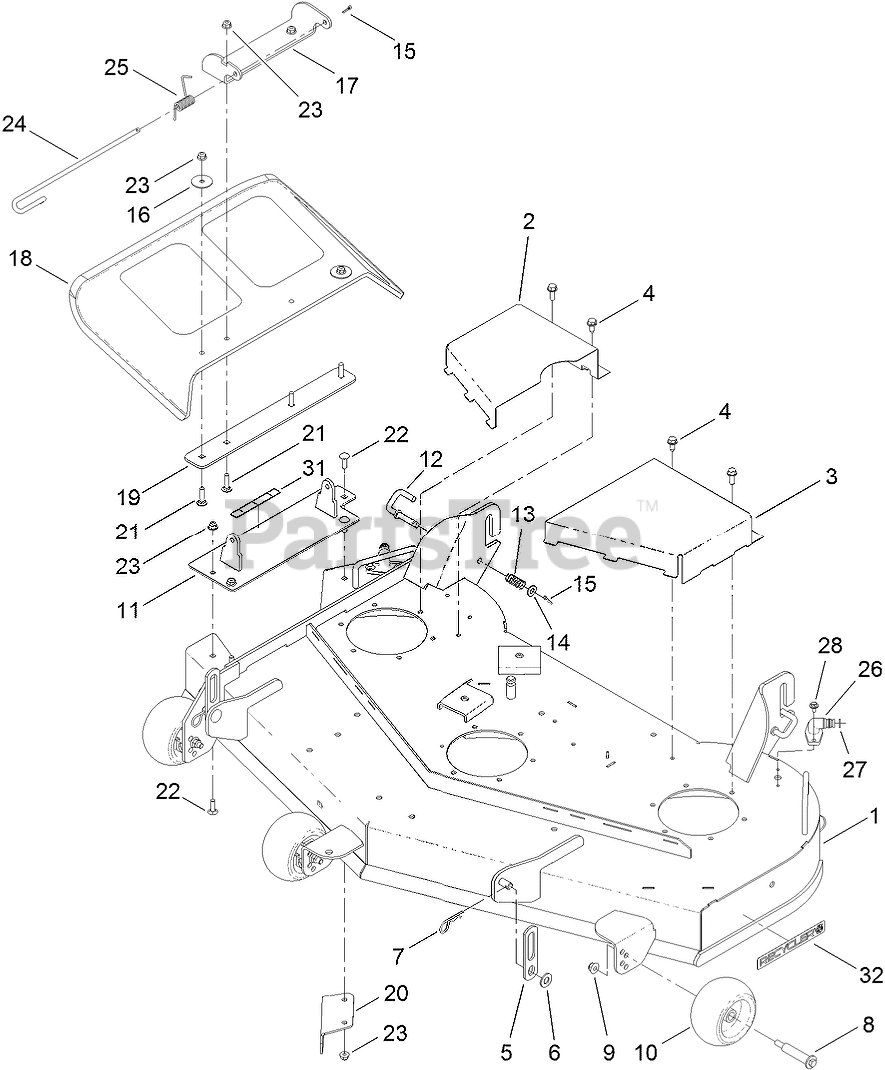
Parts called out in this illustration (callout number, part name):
1	48 INCH DECK AND DECAL ASM
2	COVER-BELT, RH
3	COVER-BELT, LH
4	SCREW-HWHTF
5	LINK-LIFT
6	WASHER-FLAT
7	PIN-COTTER
8	BOLT-SHOULDER
9	NUT-HF, NI
10	ROLLER-SCALP, ANTI
12	PIN-LATCH
13	SPRING-COMPRESSION
14	WASHER-FLAT
15	PIN-COTTER
16	WASHER-FLAT
17	BRACKET-DEFLECTOR, UPPER
18	DEFLECTOR
19	PLATE-DEFLECTOR
20	BAFFLE-CUTOFF
21	SCREW-CARR
22	SCREW-CARR
23	NUT-HF, NI
24	PIN-CHUTE
25	SPRING-TORSION
26	FITTING-WASHOUT
27	O-RING
28	SCREW-HHFTF
31	DECAL-DANGER
32	DECAL-RECYCLER
